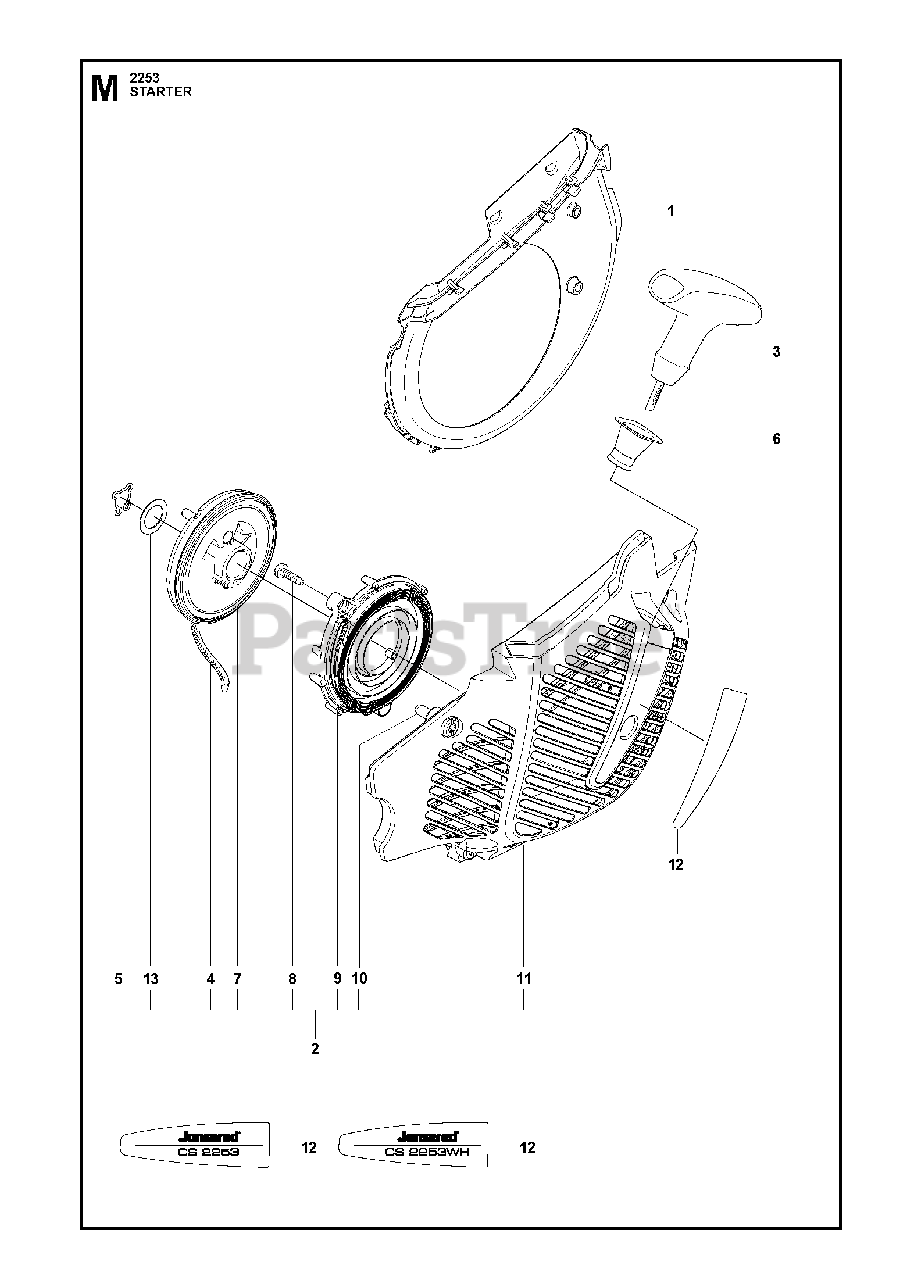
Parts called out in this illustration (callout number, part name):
1	COOLING AIR CONDUCTOR
3	STARTER HANDLE
4	STARTER ROPE
5	CLIPS
6	SLEEVE
7	STARTER PULLEY ASSY
8	SCREW
9	SPRING CASSETTE ASSY
10	SCREW
13	WASHER
